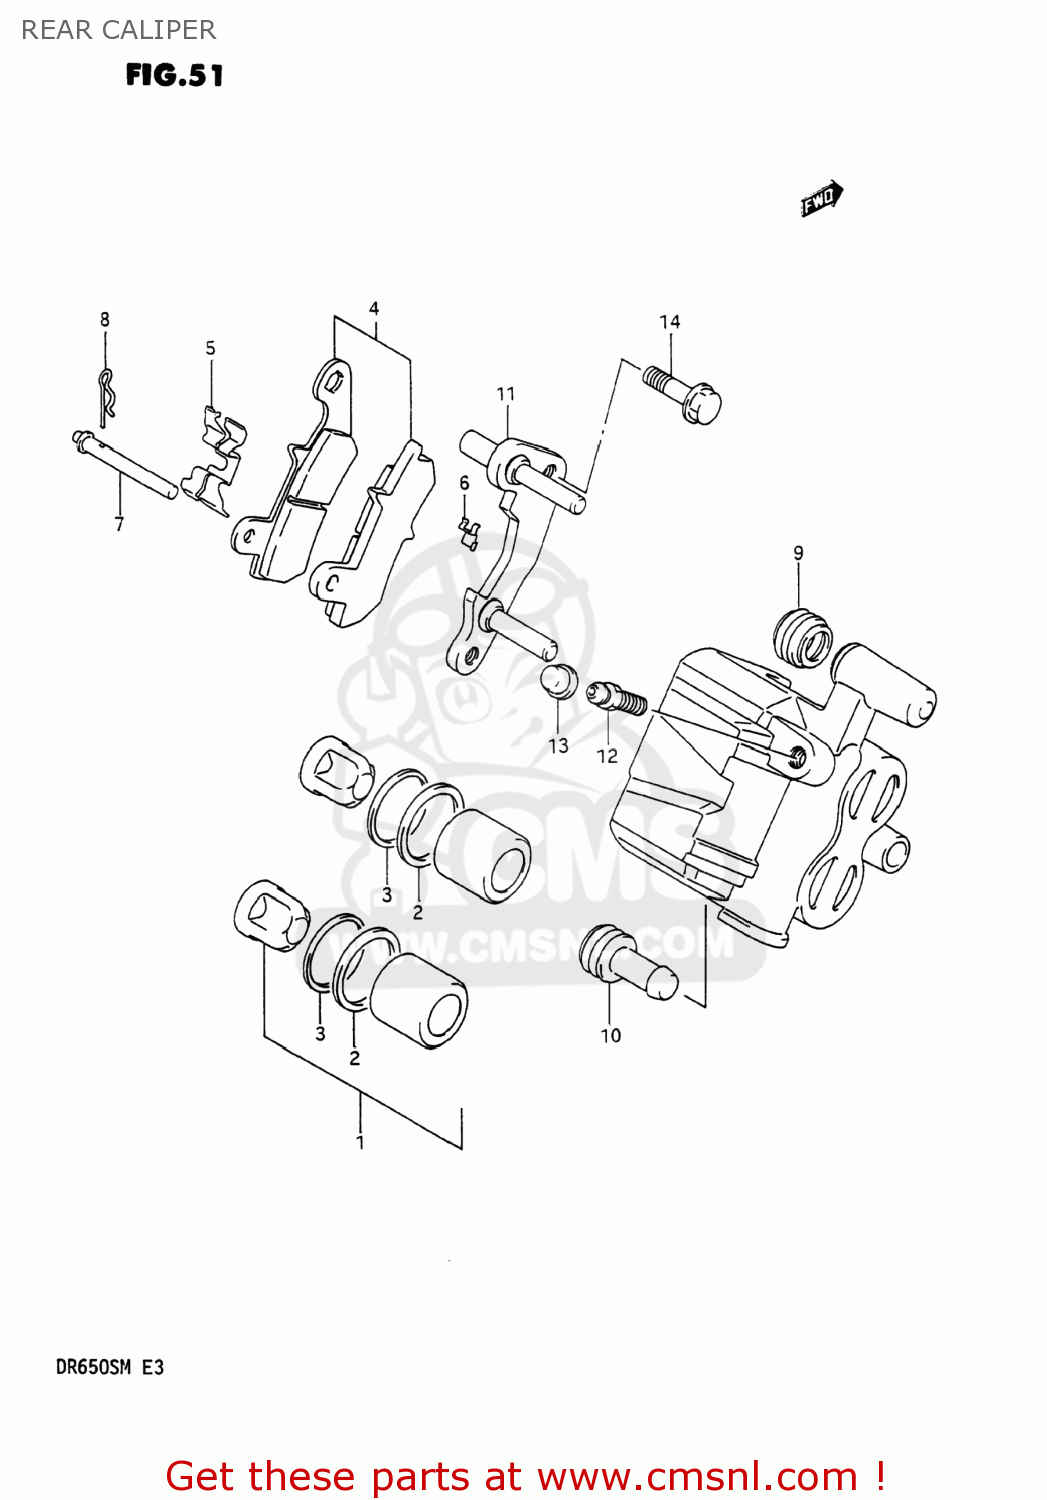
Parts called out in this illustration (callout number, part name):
1	BRAKE PISTON SET
2	SEAL,PISTON
3	SEAL,WIPER
4	PAD SET (NAS)
5	SPRING,PAD
6	GUIDE,PAD
7	PIN,PAD
8	CLIP,PAD PIN
9	BOOT,AXLE
10	INSULATOR,AXLE
11	CARRIER
12	BLEEDER
13	CAP,BREATHER
14	BOLT(8X22)
